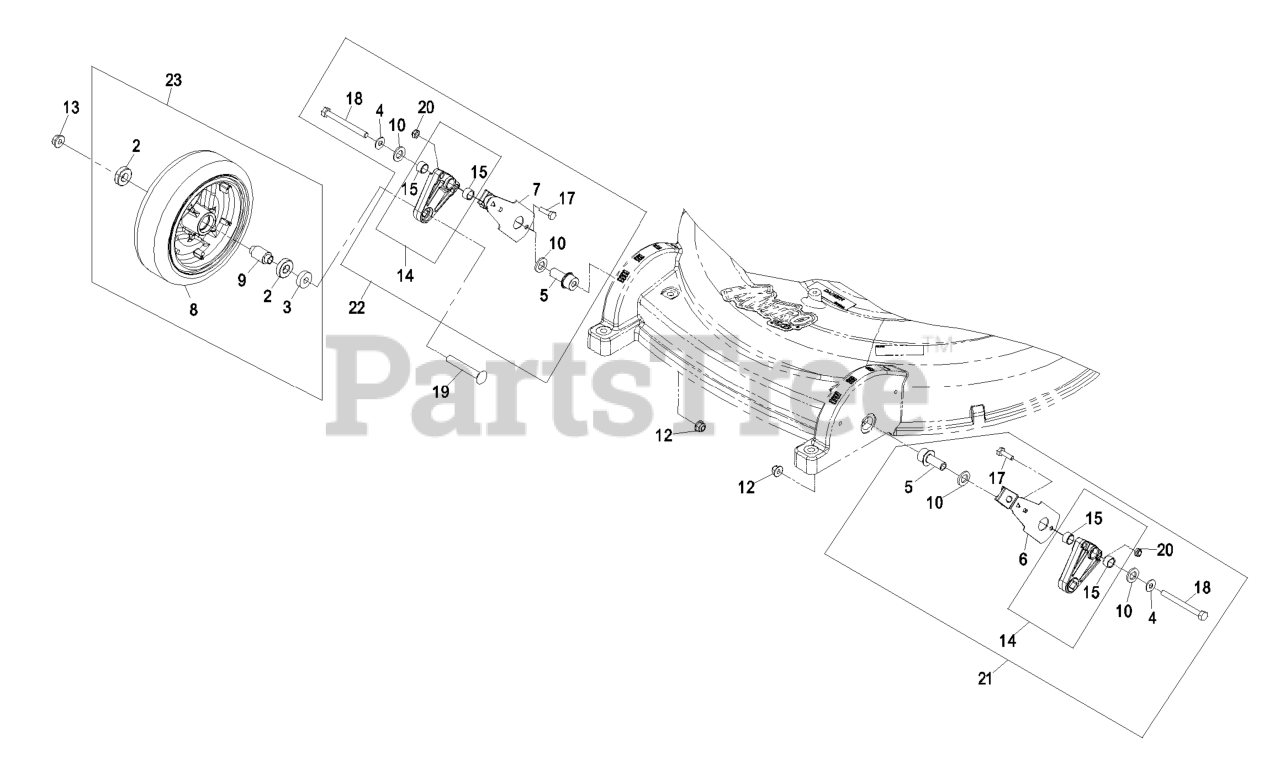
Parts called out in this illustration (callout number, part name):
2	BEARING-WHEEL
4	WASHER-FLAT
5	BUSHING-PIVOT, WHEEL
6	KIT,SPRING ARM FRONT LH
7	KIT,SPRING ARM FRONT RH
8	ASM,8" WHEEL AND TIRE
9	SPACER-WHEEL, FRONT
10	WASHER-THRUST, NYLON
12	NUT-HF, NI
13	NUT-HF, NI
15	BEARING,SLEEVE
17	SCREW-HH
18	SCREW-HH
19	SCREW-CARR
20	NUT-LOCK, NI
23	8 INCH WHEEL ASM
